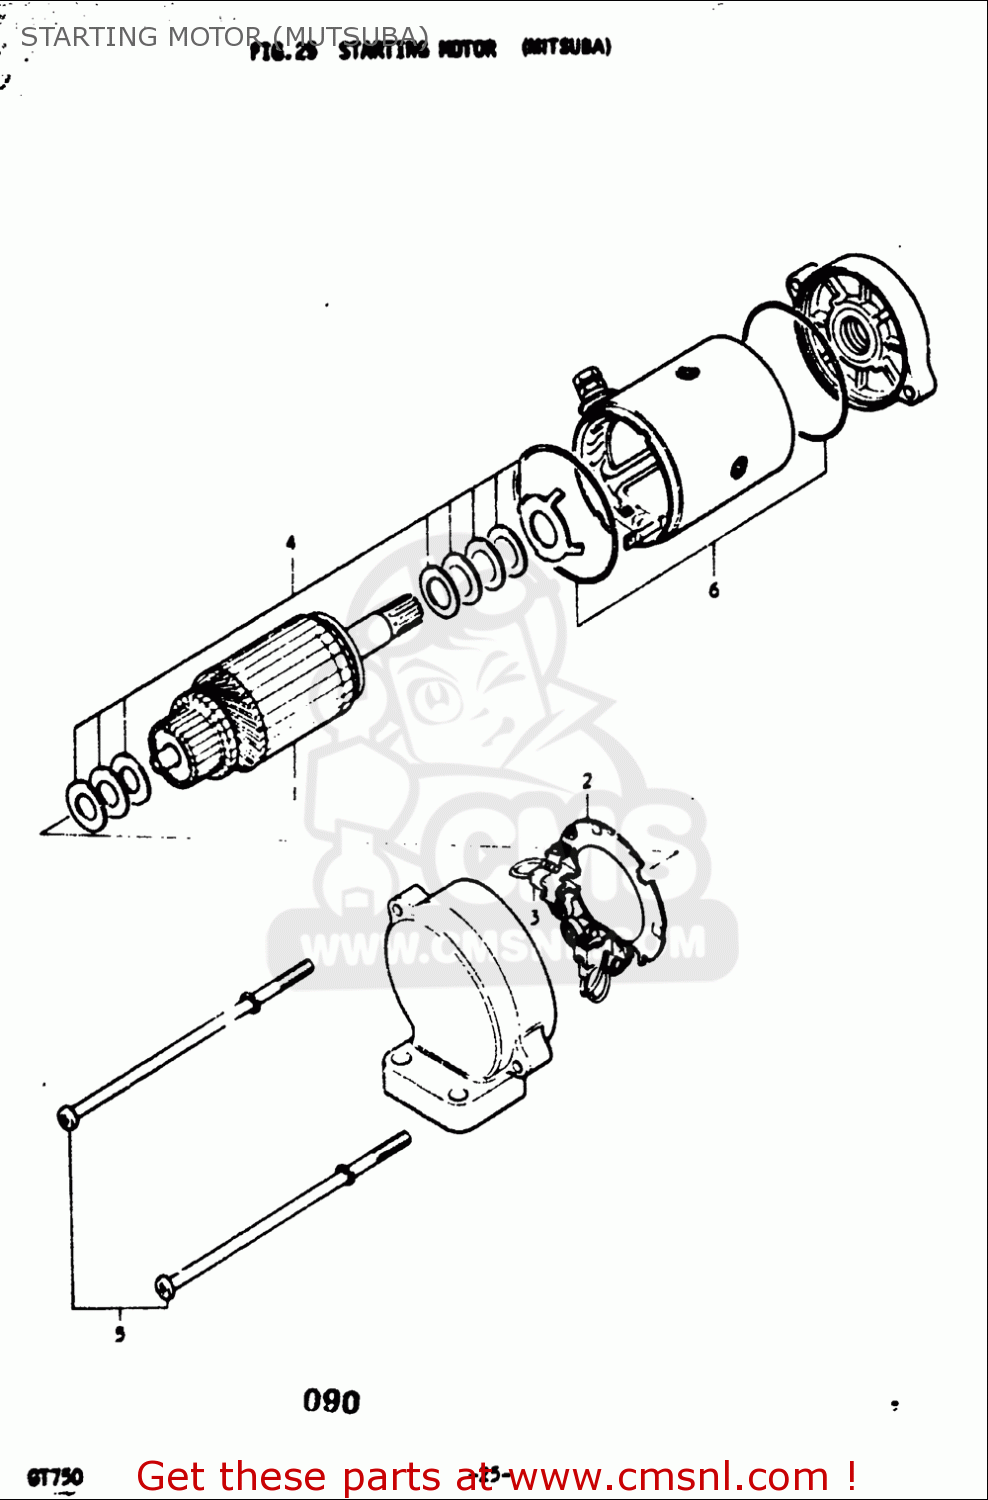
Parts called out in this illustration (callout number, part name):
2	HOLDER ASSY
3	BRUSH SET
5	BOLT
6	O RING
